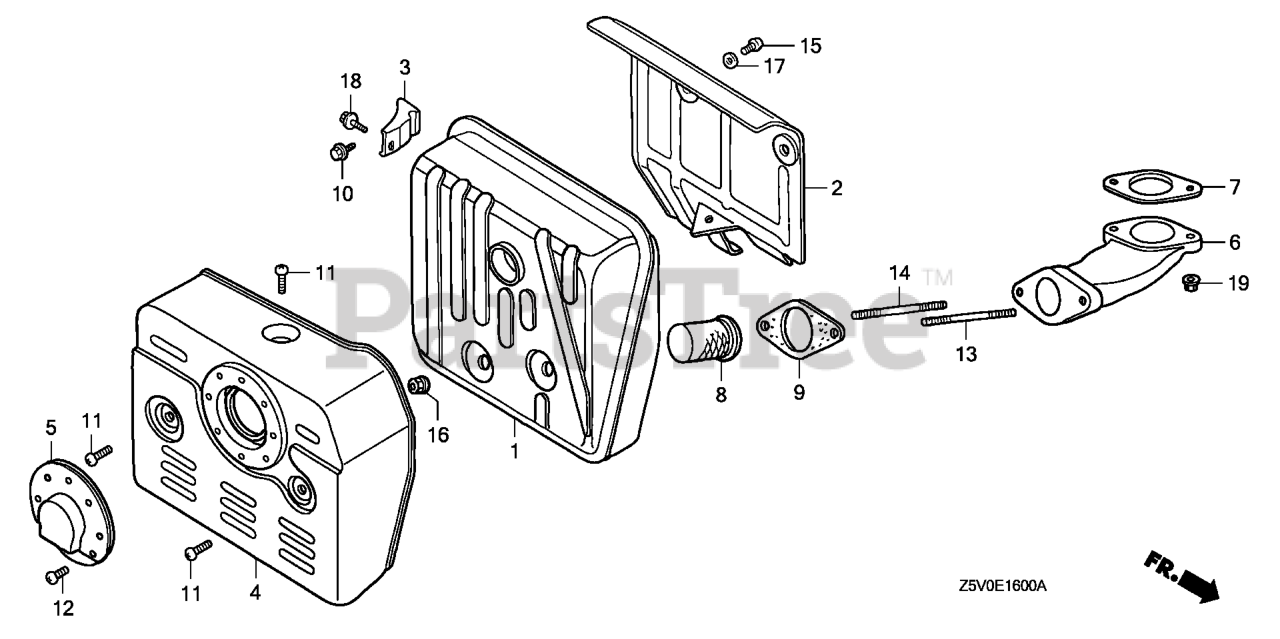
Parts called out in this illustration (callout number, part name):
1	MUFFLER
2	SEPARATOR, MUFFLER
3	STAY, MUFFLER
4	PROTECTOR, MUFFLER
5	CAP, MUFFLER
6	PIPE, EX.
7	GASKET, EX. PIPE
9	GASKET, EX. PIPE
10	BOLT, FLANGE (8X16)
11	SCREW, TAPPING (5X8)
12	SCREW, TAPPING (4X6) (TO INSTALL OPTIONAL SPARK ARRESTER)
13	BOLT, STUD (8X60)
14	BOLT, STUD (8X70)
15	SCREW, PAN (6X6)
16	NUT, FLANGE (8MM)
17	WASHER, PLAIN (6MM)
18	BOLT, FLANGE (8X14)
19	NUT, FLANGE (8MM)
